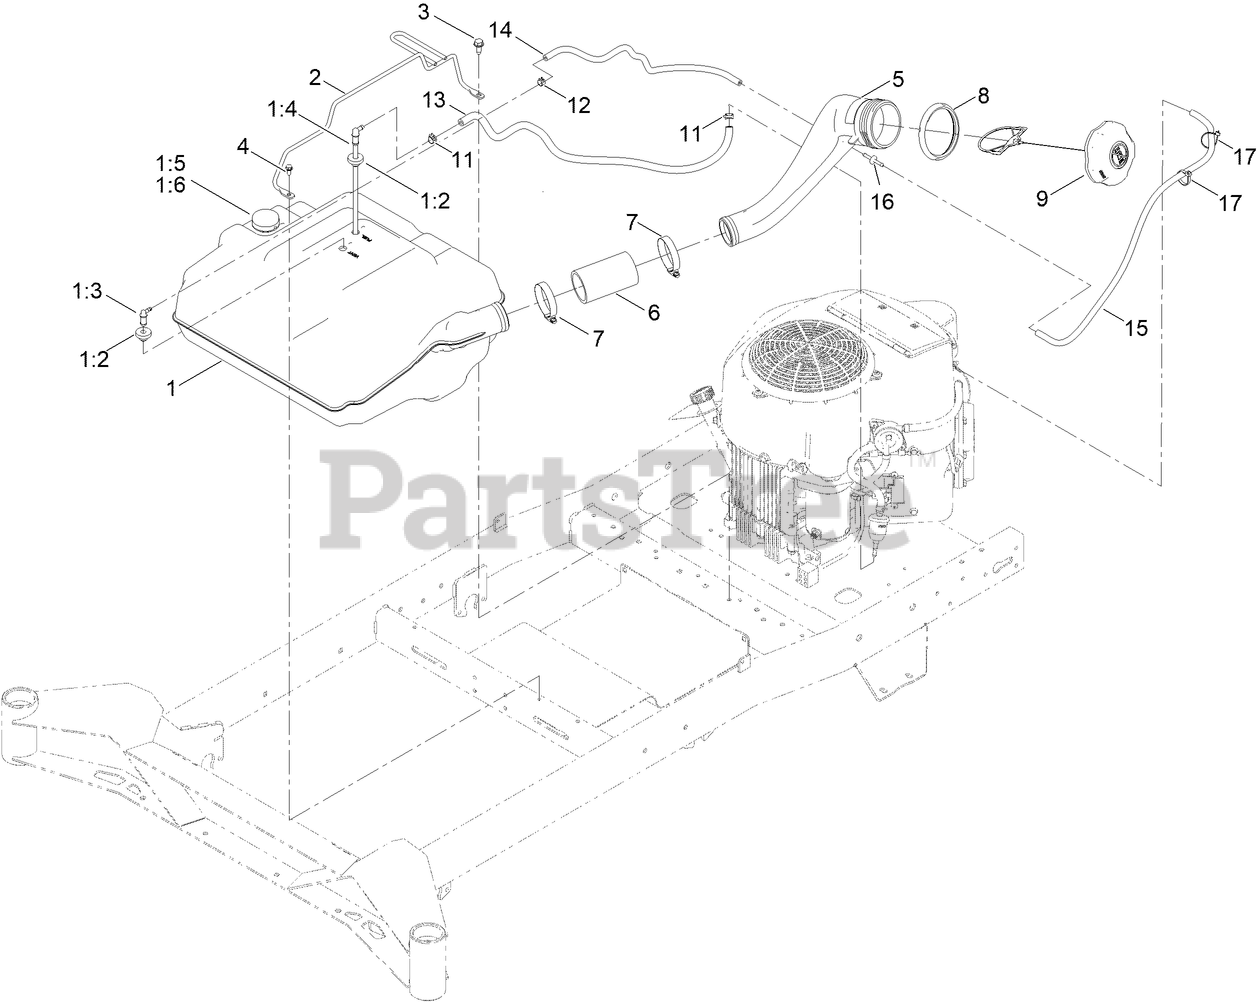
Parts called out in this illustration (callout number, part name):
1	TANK ASM-FUEL
1:2	BUSHING
1:3	FITTING-ELBOW 90
1:4	GROMMET-FUEL
1:5	REMOTE GAUGE ASM
1:6	FITTING - PICKUP, FUEL
2	HOLD DOWN ASM
3	SCREW-HWHTF
4	SCREW-HWH
5	NECK-FILLER, FUEL
6	HOSE-FILLER, FUEL
7	CLAMP-HOSE
8	RING-RETAINING
9	CAP-FUEL, RATCHETING
11	CLAMP-HOSE
12	CLAMP-HOSE
13	HOSE-FUEL
14	HOSE-FUEL
15	HOSE-FUEL
16	ADAPTER ORIFICE
17	TIE-CABLE
